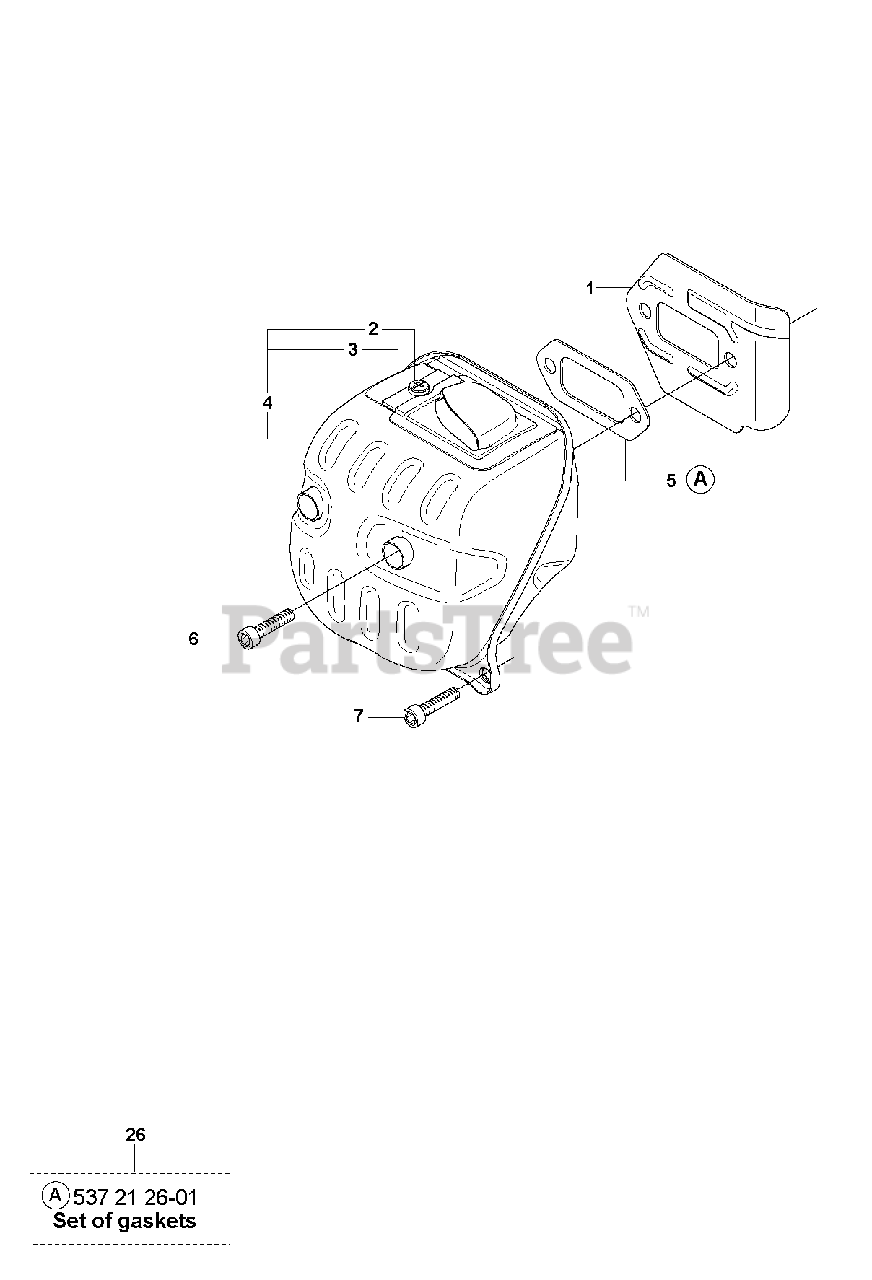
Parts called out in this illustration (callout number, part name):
2	SCREW
3	SCREEN
4	MUFFLER ASSY (FF CE)
4	MUFFLER ASSY (DF US)
5	GASKET
6	SCREW MC6S 6X20
26	GASKET KIT
